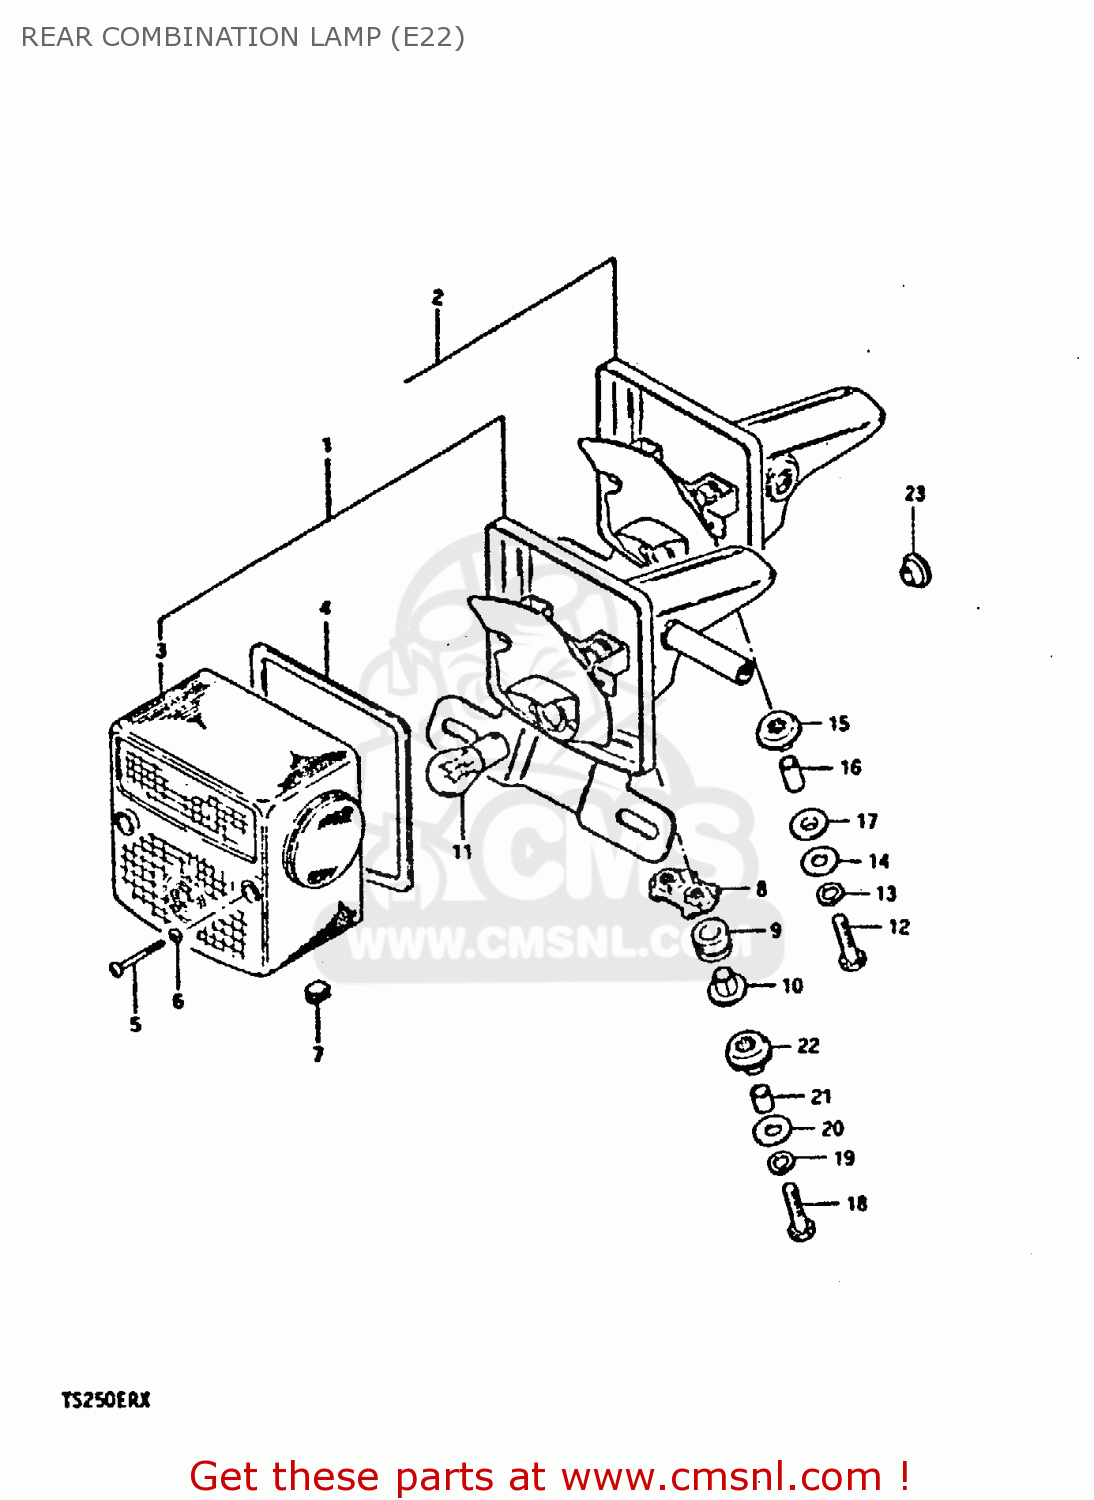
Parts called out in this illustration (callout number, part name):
1	LAMP ASSY, REAR COMBINATION
2	LAMP ASSY, TAIL
3	LENS
4	GASKET (NAS)
5	SCREW (4X55)
6	GASKET (NAS)
7	GROMMET,REAR COMBINATION LAMP
8	PLATE
9	CUSHION
10	SPACER
11	BULB (6V,21/5W)
12	BOLT
13	LOCK WASHER
14	WASHER (6.5X20X1.2)
15	CUSHION
16	SPACER
17	CUSHION
18	BOLT
19	LOCK WASHER
20	WASHER (6.5X20X1.2)
21	SPACER
22	CUSHION
23	GROMMET
